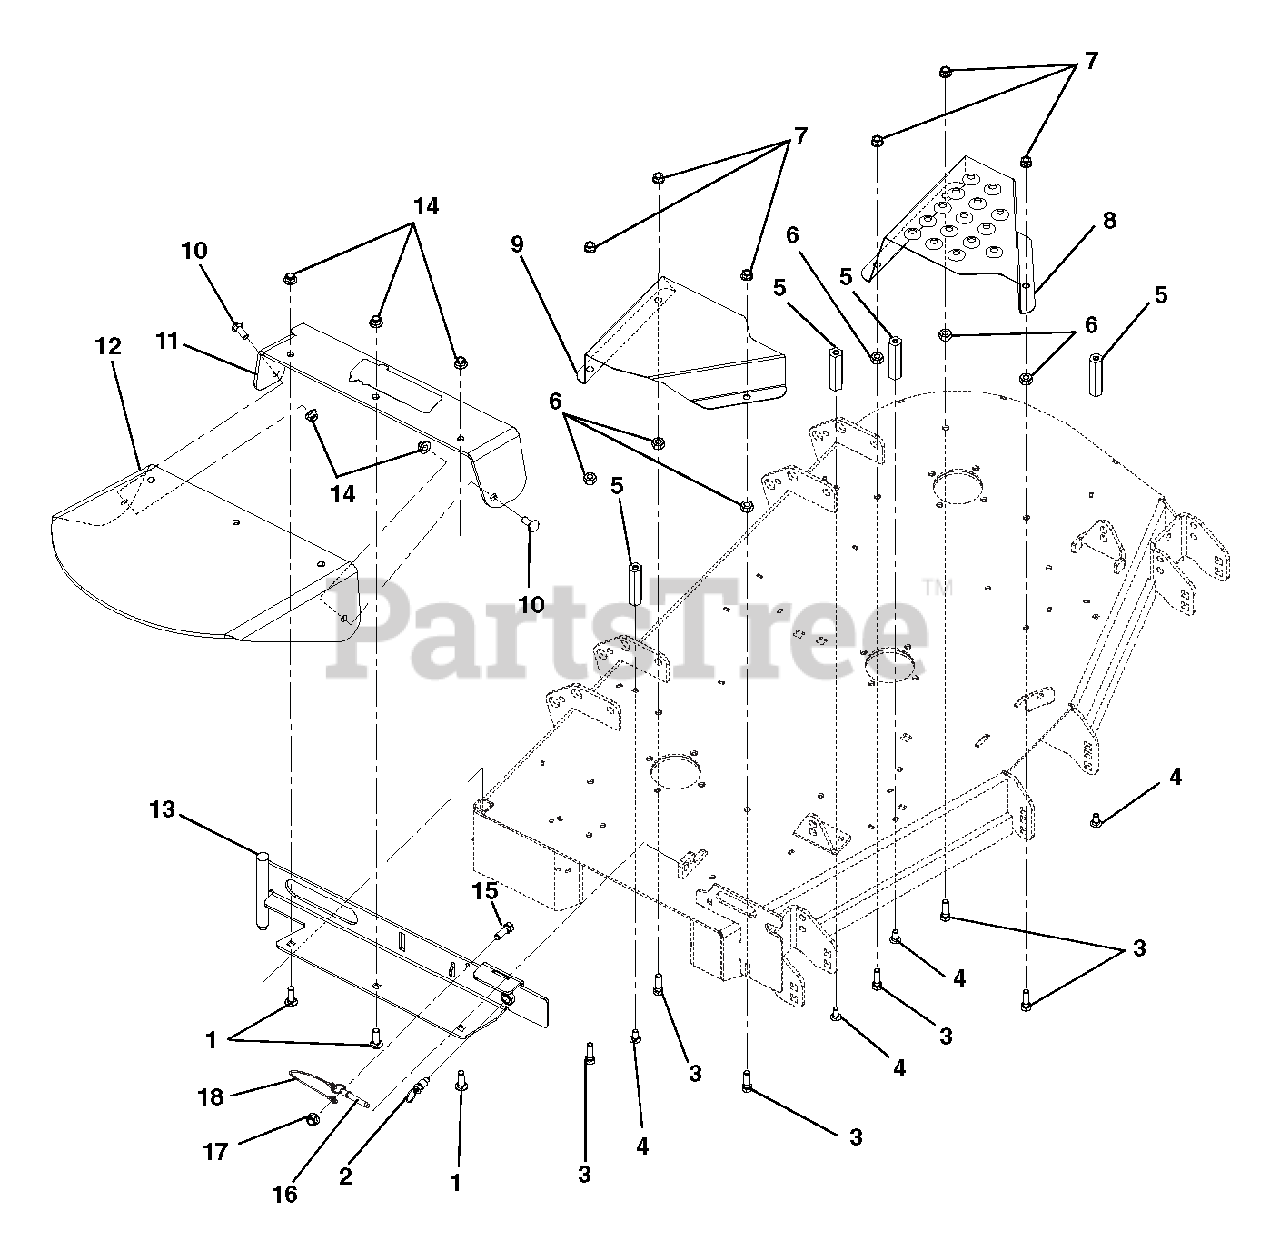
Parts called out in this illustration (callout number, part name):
1	@BLT-RDHDSQNK .38-16X1.25 G5YZ
2	PULL PIN,.50-13THDX.310 PLNGR
3	@BLT-HEX .38-16X1.25 GR5 YWZC
4	BLT,RDHDSQNK .31-18X.75 LOCTIT
5	NUT, COUPLING .31-18 X 3.00
6	NUT-HEAVY HEX .38-16 YWZC
7	@NUT-SPNLK-FLG .375-16 YWZC
8	GUARD,LH DECK BELT,44-52
9	GUARD-44-52 RH SPINDLE SHEAVE
10	@BLT-RDHDSQNK .38-16X1.00 G5YZ
11	RUBBER DISCH CHUTE SUPPORT-RED
12	CHUTE, RUBBER DISCHARGE
13	44"-48" DISCH CHUTE MTG WMT-RD
14	@NUT-LK-NYL-FLG .38-16 YWZC
15	@BLT-HEX .25-20X.75 GR5 YWZC
16	PIN, SPRING BALL .375OD X 1.50
17	@NUT-LK-TOP-FLG .25-20 YWZC
18	CABLE, 6.0 LANYARD, NYLON
